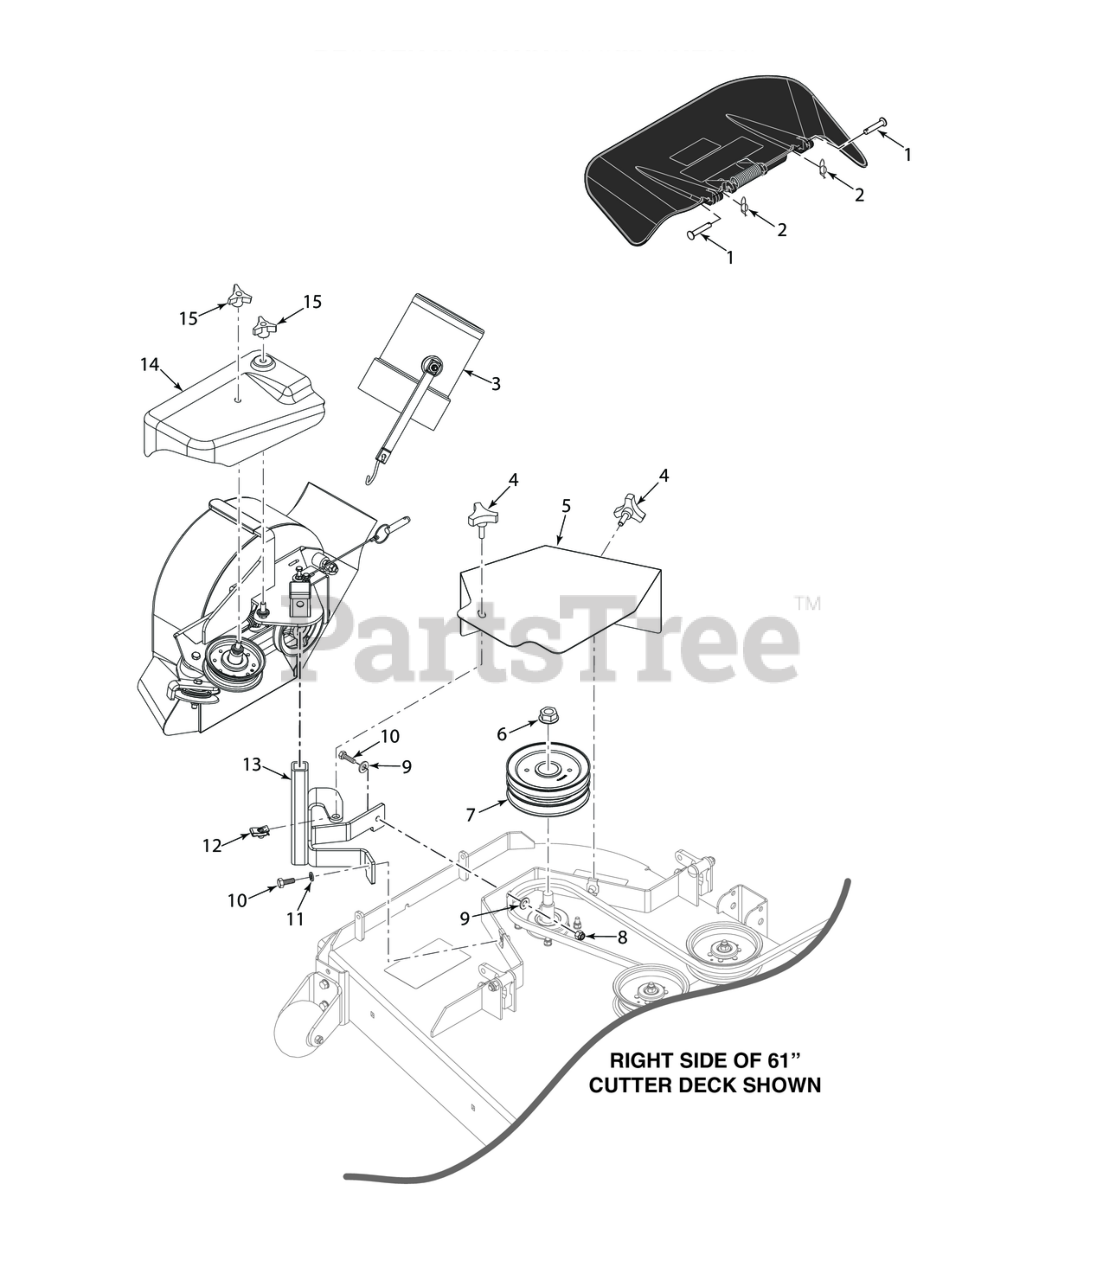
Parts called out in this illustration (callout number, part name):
1	Clevis Pin, 5/16 x 1-1/2"
2	Pin, Rue Cotter 5/16 Dia.
3	Adapter, Blower GC-STC,
4	Knob, w/stud 3/8-16 x 1-1/4"
5	Belt Cover - 52
6	Nut, 3/4-16 Spriral Lock
7	Pulley, Double Groove - 52
8	HEX NUT, ELASTIC STOP LOCK, 3/8-16
9	Flatwasher, 3/8" Special (.391 x .938 x .105)
10	Bolt, Hex Head 3/8-16 x 1-1/4", Kawasaki FX / FS
11	Lockwasher, 3/8" Spring, Kawasaki FX / FS
12	U-Nut, 3/8-16 (short)
13	Mounting Post Assembly, Blower - 52
14	Belt Cover - 52
15	Wing Nut, 3/8-16 (Small) Top side
